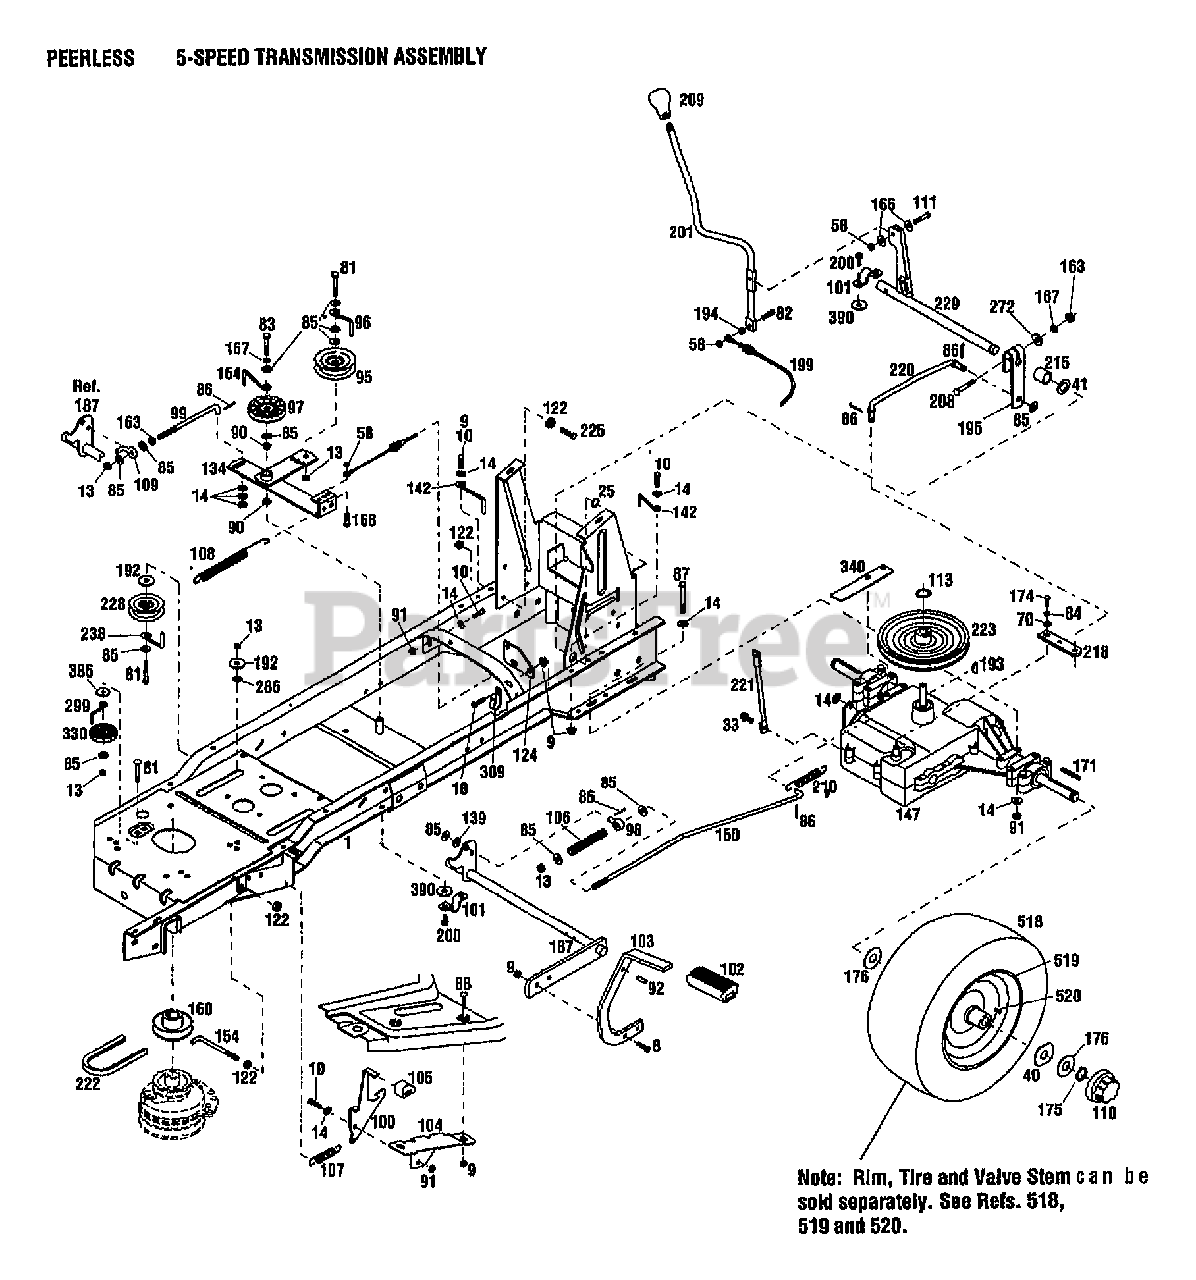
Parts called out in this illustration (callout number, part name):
1	ASSM-FRAME LTX
8	SCR-HH 5/16-18X1.0 G5 ZP
9	NUT-HFLK 5/16-18 ZP
10	SCR-HHC 5/16-18X.75 GR 5 ZP
13	NUT-LOCK 3/8-16
14	WASHER-FLAT 5/16 SAE
25	RING-RETAIN EXT .707 ID
33	SCR-HFLK 5/16-18X.75
40	WASHER-SPEC .75X2.50
41	WASHER-1.38 X.765X .06 ZP
58	NUT-HT LK 1/4-20
70	WASHER-FLAT 1/4 SAE
81	SCR-HH 3/8-16X2.0 G5 ZP
82	SCR-HH 1/4-20X1.0
83	SCR-HH 3/8-16X1.75 G5 ZP
84	WASHER-LK .25 ZP
85	WASHER-FLAT 3/8 SAE
86	PIN-COTTER .09X.75 ZP
87	SCR-HH 5/16-18X2.75 G5 ZP
88	SCR-CARR 5/16-18X.62 G2 ZP
90	BUSHING-.5X.5 NYLON FLNG
91	NUT-TOP/LK 5/16-18 ZP
92	PIN-DRIVE .312X.75
96	GUIDE-BELT
97	PULLEY-IDLER
98	SWIVEL
99	ROD-CLUTCH
100	LATCH-BRAKE LOCK
101	CLIP-CLAMP .75 ID
102	PAD-FOOT PEDAL
103	PEDAL-BRAKE
104	BRKT-BRAKE LOCK
105	PAD-BRAKE
106	SPRING-COMPRESSION
107	SPRING-EXTENSION
108	SPRING-EXTENSION
109	ROD-PIVOT
110	CAP-HUB
111	SCR-HFLK 1/4-20X1.00
113	RING-RETAIN .625 ID
122	NUT-HFLK 3/8-16 ZP
124	SUPPORT-CABLE
134	PLATE-IDLER
139	WASHER-FLAT .375DIA
142	GUIDE-BELT
147	TRANSAXLE
150	ROD-BRAKE
154	RETAINER-CLUTCH
160	PULLEY-ENGINE
163	NUT-HEX 3/8-16 ZP
164	GUIDE-BELT
166	WASHER-FLAT 1.25X.28X.062 ZP
167	WASHER-LK .375 @ DEPL
168	SCR-HH 1/4-20X.75 G5 ZP
171	KEY-.188 SQ X 2.0
174	SCR-HHC 1.4-28 X .50
175	RING-RET."E".577 ID
176	WASHER-1.87X.765X.06 SPECIAL
187	ASSM-BRAKE PEDAL
192	WASHER-1.12X.378X.125
193	KEY-WOODRUFF .188X.75
194	NUT-HEX 1/4-20 ZP
195	ARM-SHIFT SHAFT
199	CABLE-SHIFT
200	SCR-HFLK 5/16-18X.75
201	ARM-SHIFT
208	BOLT-CARR 3/8-16X2 1/4
210	SPRING-EXTENSION
215	SPACER
218	ARM-TRANSMISSION
220	ROD-SHIFT
221	SUPPORT-TRANS
223	SHEAVE-TRANSMISSION
225	SCR-HH 3/8-16X1.25
228	IDLER-SHEAVE 3" X 1"
229	SHAFT-PIVOT
238	GUIDE-BELT
272	WASHER-FLAT 1.25X.406X.179
286	WASHER-.75X.406X.092
299	GUIDE-BELT
309	CLIP-J
330	PULLEY-IDLER
340	STOP-TRANSMISSION
386	WASHER-1.06X.531X.1 ZP
390	WASHER-.632X.39X.0329
518	TIRE-20X8.00-8
519	RIM-TIRE
520	STEM-VALVE
